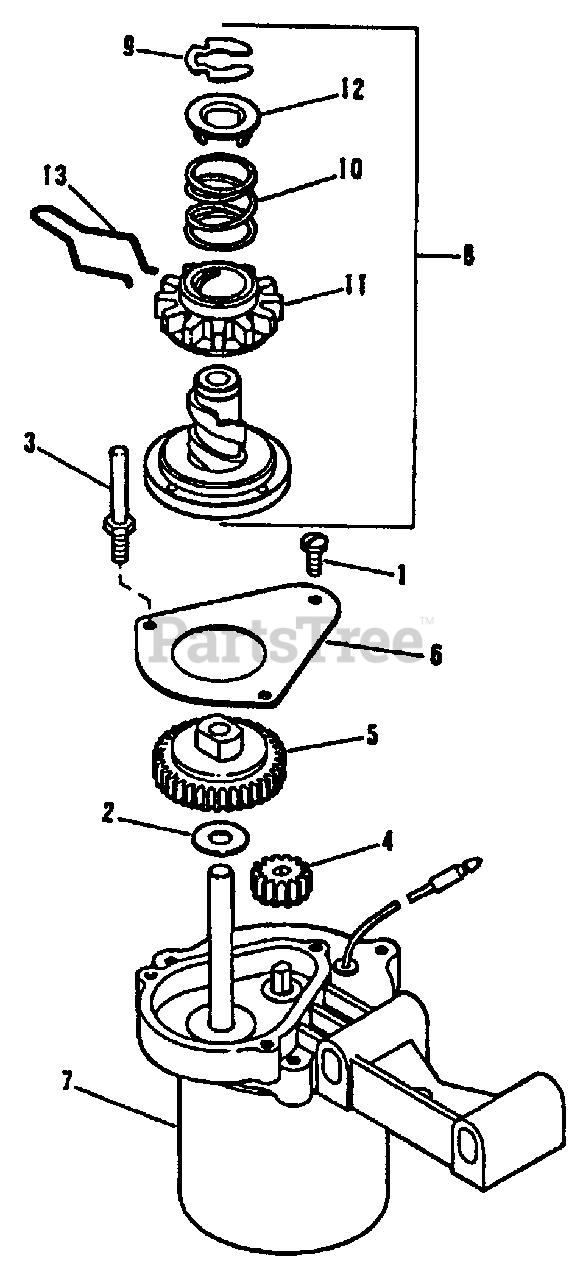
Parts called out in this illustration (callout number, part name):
1	Screw
2	Washer-Thrust
3	Stud-Drag Spring
4	Pinion
5	Gear-Driven
6	Plate-Gear Cover
7	Motor Housing and Pin Assembly
8	Pinion, Spring and Clutch Assembly
9	Retaining Ring
10	Spring-Pinion
11	Pinion
12	Stop Washer
13	Spring-Drag
